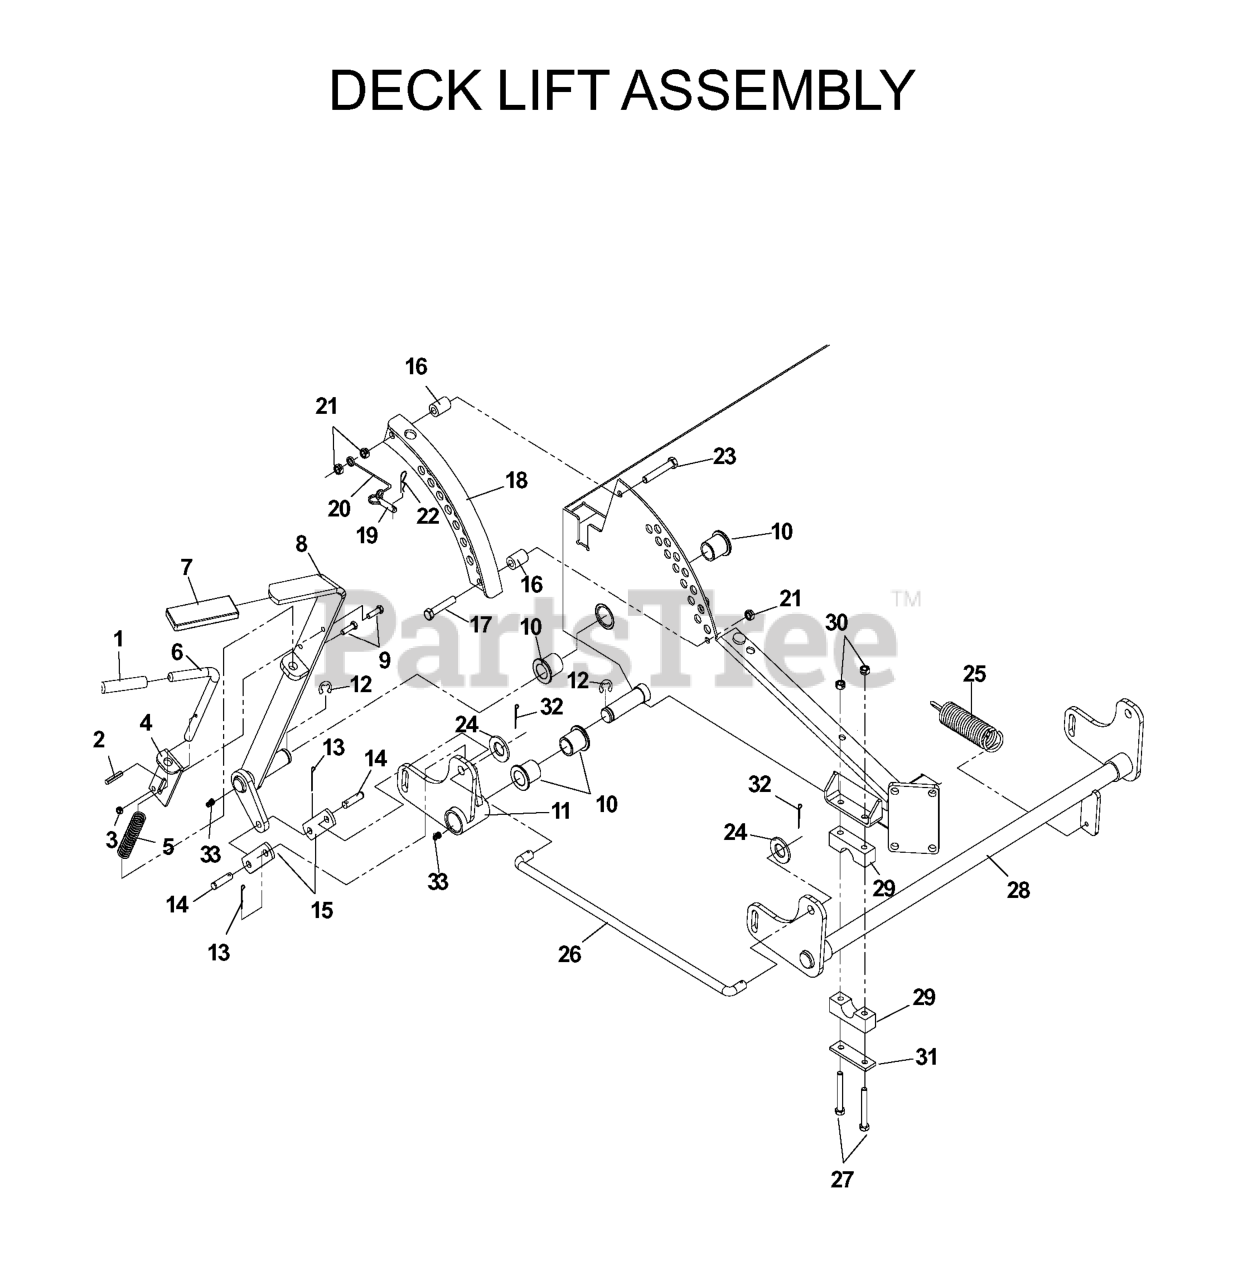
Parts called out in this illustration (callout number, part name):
3	NUT 1/4C CENTER LOCK
4	PIN MT, UPPER
8	LIFT LEVER WELDMENT
9	HCS 1/4C X 3/4 HCS
10	BUSHING, FLANGED
11	BELLCRANK, RR-BLACK
12	E-RING 7/8
13	RP_COTTER PIN 1/8 X 3/4
14	CLEVIS PIN 3/8 X 1 1/8
17	HCS 3/8C X 2
18	ADJUSTMENT PLATE
21	NUT 3/8-16 NYLOC
22	HAIRPIN #4
23	HCS 3/8C X 2 1/2
26	DECK LIFT LINK
27	HCS 5/16C X 2-3/4
28	LIFT SHAFT
29	PILLOW BLOCK
30	NUT 5/16 NYLOC
31	REINFORCEMENT BAR
32	COTTER PIN
539107031	BELCRANK, LR
